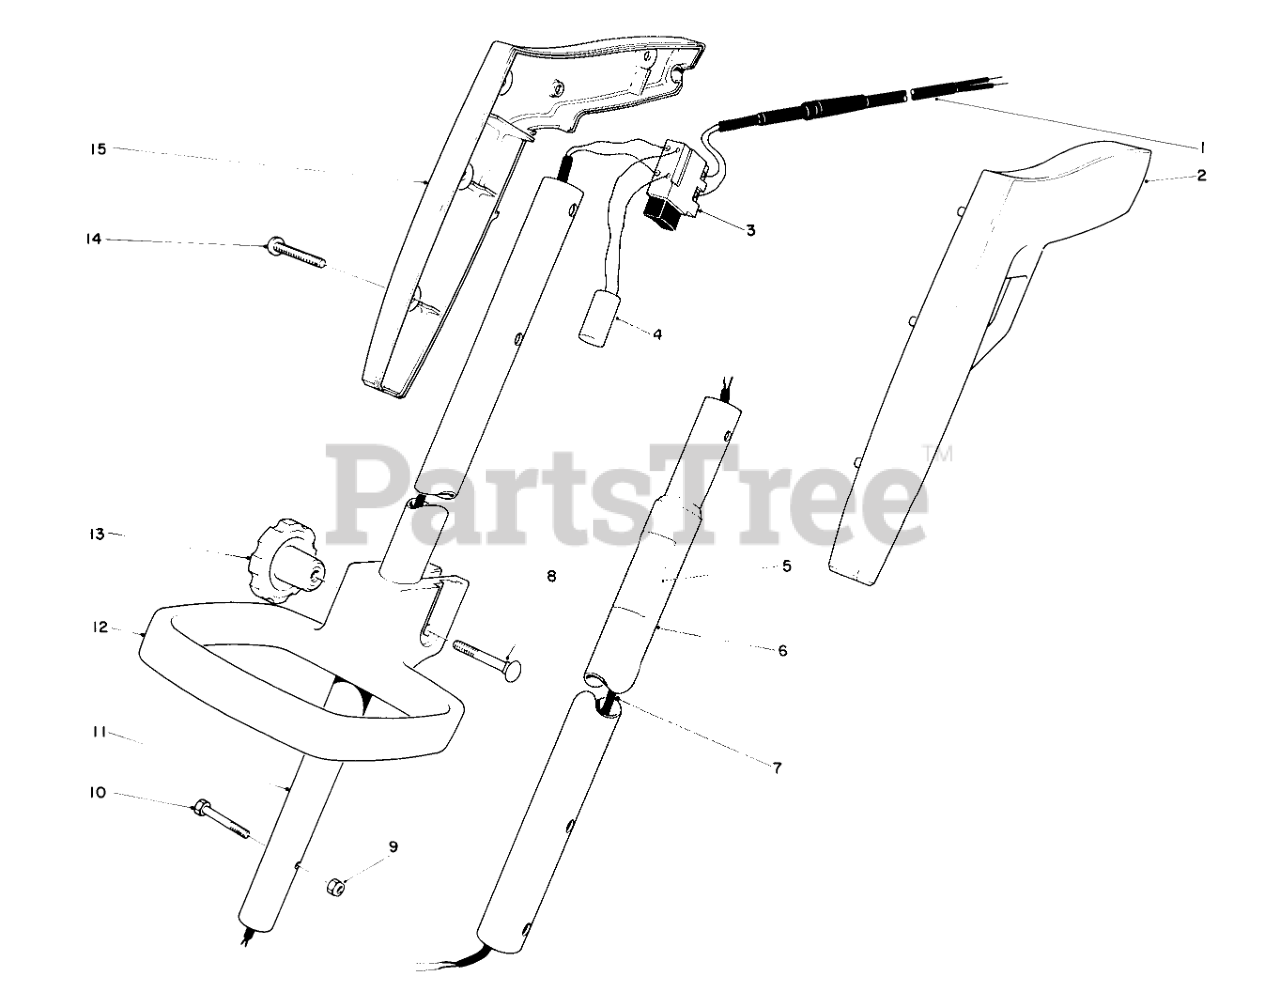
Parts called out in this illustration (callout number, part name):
1	Power Cord
2	Grip-Left Hand
3	Switch
4	Suppressor
5	Caution Decal
6	Tube-Lower
7	Wiring Harness
8	BOLT-CARR
9	NUT-LOCK, NI
10	HEX HD MACHINE SCREW
11	Tube-Upper
12	ADJUSTABLE HANDLE
14	Screw
15	Grip-Right Hand
